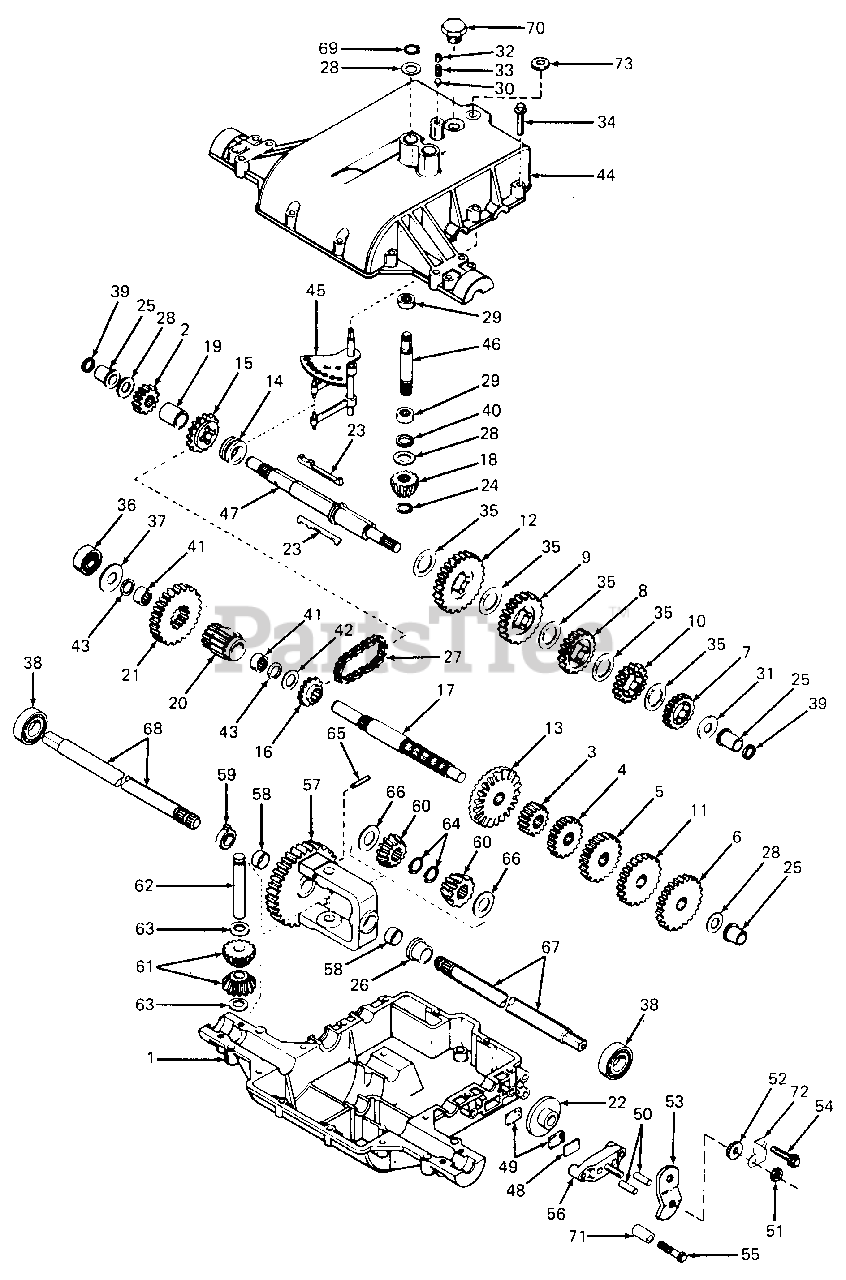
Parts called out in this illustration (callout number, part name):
1	Case, Transaxle
2	Gear, Spur (15 teeth)
3	Gear, Spur (12 teeth)
4	Gear, Spur (20 teeth)
5	Gear, Spur (25 teeth)
6	Gear, Spur (30 teeth)
7	Gear, Spur (20 teeth)
8	Gear, Spur (25 teeth)
9	Gear, Spur (30 teeth)
10	Gear, Spur (22 teeth)
11	Gear, Spur (28 teeth)
12	Gear, Spur (37 teeth)
13	Gear, Bevel (42 teeth)
14	Collar, Shift
15	Sprocket (18 teeth)
16	Sprocket (9 teeth)
17	Shaft, Counter
18	Bevel Pinion, Input
20	Pinion, Output
21	Gear, Output
22	Disk, Brake
23	Key
24	Ring, Retaining
25	Bushing, Flanged
26	Bushing, Flanged
27	Chain, Roller
28	Washer, Thrust
29	Bearing, Needle
30	Ball, Steel
31	Washer, Thrust
32	Screw, Set, 3/8-16 X 3/8
34	Screw, Hex Hd Thread Forming, 1/4-20 X 1-1/4
35	Washer, Thrust
36	Bearing, Ball
37	Washer, Flat
38	Bearing, Ball
39	Seal, Square Cut
40	Seal, Square Cut
41	Bearing, Needle
42	Washer, Flat
43	Seal, Square Cut
44	Cover, Transaxle
45	Rod & Fork Assy, Shift
46	Shaft, Input
47	Shaft, Brake
48	Plate, Brake Pad
49	Pad, Brake
50	Pin, Dowel
51	Locknut, 5/16-24
52	Washer, Flat
53	Lever, Brake
54	Screw, Hex Hd Thread Forming, 1/4-20 X 1-1/4
55	Screw, Hex Hd Thread Forming, 1/4-20 X 2-1/4
56	Holder, Brake Pad
57	Gear Assy, Differential
60	Gear, Bevel
61	Pinion, Bevel
62	Pin, Drive
63	Washer, Thrust
64	Ring, Retaining
66	Washer, Thrust
67	Axle, 14-5/8 in. Long
68	Axle, 12-3/4 in. Long
69	Ring, Retaining
70	Plug, Hex Hd, 9/16-18 Thread
72	Bracket, Brake Lever
